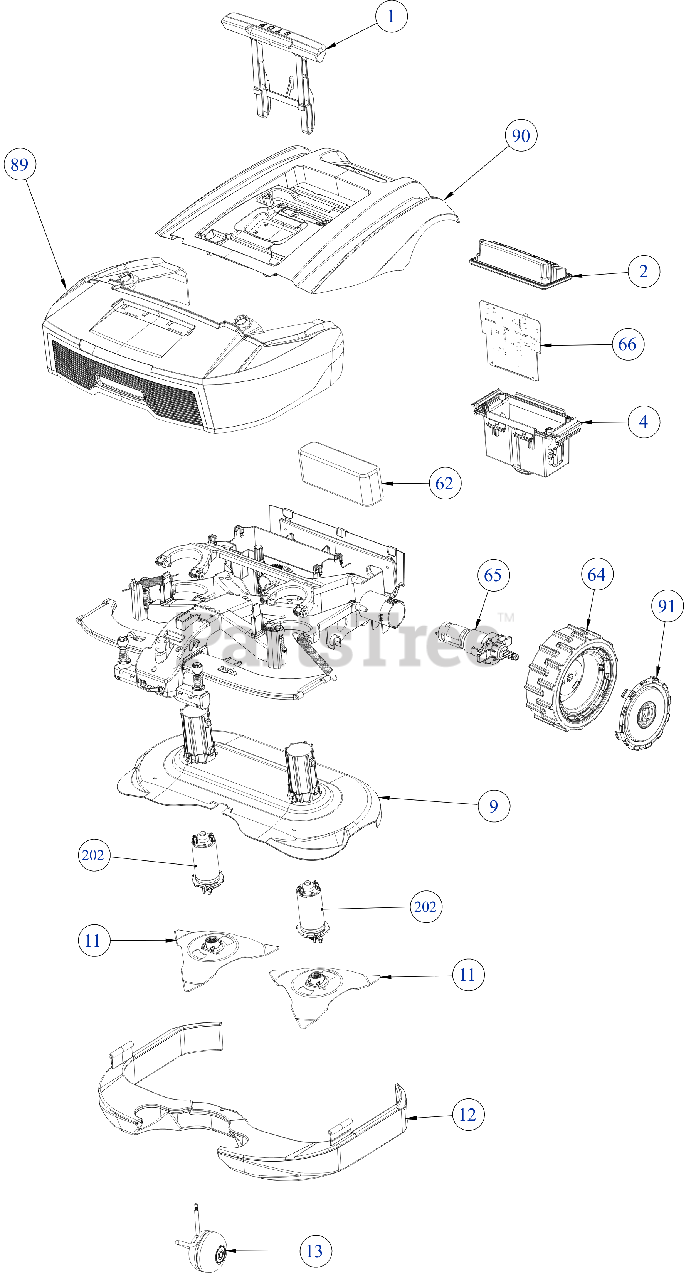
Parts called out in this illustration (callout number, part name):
1	CARRYING AND STOP HANDLE
2	LCD PANEL ASSEMBLY
4	C-BOX ASSEMBLY
5	DRIVE MOTOR ASSEMB
9	MOWING DECK ASSEMB
11	HIGH CUT BLADE SET KIT
12	FLOATER ASSEMBLY
13	FRONT WHEEL ASSEMBLY (2014)
14	WIRE LOCKER
15	MOWING UPPER ARM
16	MOWING MOTOS LOCKE
17	MOWING LOWER ARM
18	BALL JOINT ASSEMBL
19	SHAFT-PARRAL ASSEM
20	FLOATER SPRING
22	WING TO FLOATER SHAFT
23	WIRE SENSOR CAP
24	Y SHAFT TO WING
25	MOWING DECK SPRING
29	FRONT WHEEL MAGNET
31	CHASSIS ASS S MODE
34	RS DOOR SHUTTER KIT
36	C-BOX RUBBER DOOR
38	LIGHT COVER-BUMPER
39	BUMPER HANG CAVITY
40	BUZZER BRACKET
41	PIEZO BUZZER W/CAB
49	WIRE SENSORS CABLE W/HOLDERS
50	FUSE-BATTERY CABLE
51	MAIN BOARD TO DRIVE MOTOR CABLE
52	MAIN BOARD TO BATTERY CELLS CABLE
55	FUSE THREAD
56	FUSE-32V/20A FAST
57	FRONT WHEEL SLEEVE
62	BATTERY-RS612/RS62
64	POWER WHEELS (W/CAP)
65	HD DRIVE MOTOR ASMALUMINUM SPLINE
66	RS MAIN RED (2018)
67	FRONT BOARD S (2018 RED)
71	MAIN BOARD TO FRT WHEEL CABLE (18)
72	RS COMM/GSM SPLIT CABLE PCG6200
73	GSM/RCM (ALL MODELS)
89	RS CC BUMPER ASSEMBLY (BLACK)
90	RS CC TOP SHELL ASSEMBLY (BLACK)
91	RS CC WHEEL PLATE + RING
202	MOWING MOTOR BRUSH
203	POWER BOX HANGING BRACKET
204	SCREW + "DIBEL" X 2 KIT
207	MINI JUMPER 2.54MM
208	STAKE-PERIMETER SW
210	PERIMETER SWITCH (ESB5009F)
211	BATTERY PACK-PERIM
212	PERIMETER SWITCH B
213	PERIMETER SWITCH STICKER
